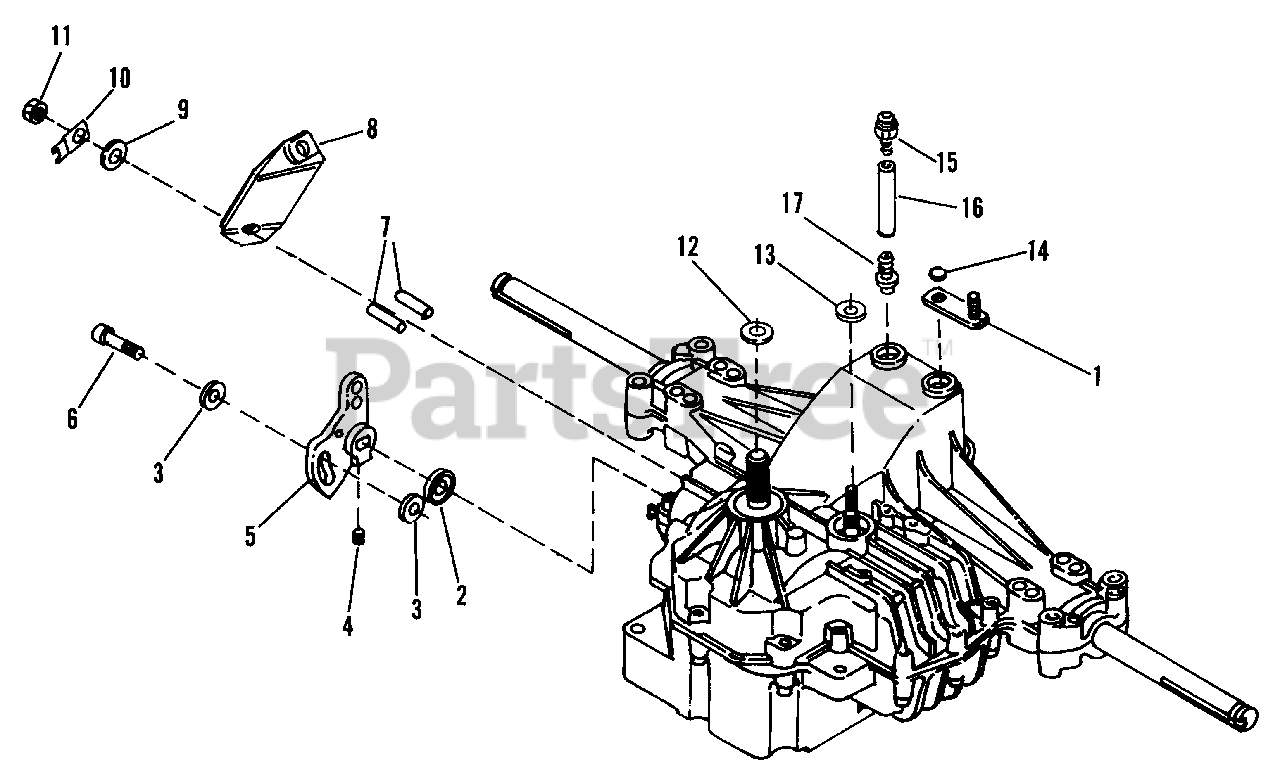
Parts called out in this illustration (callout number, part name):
1	ARM, Bypass
3	PUCK, Dampener
5	ARM, Control
6	SCREW, Soc. Hd.
7	ACTUATOR PIN
9	WASHER, 7/16 x 7/8 x 1/16
10	LOCKING STRAP
11	NUT, Hex, Lock, 5/16-24
14	RING, Retaining
15	FITTING, Vent Plug
